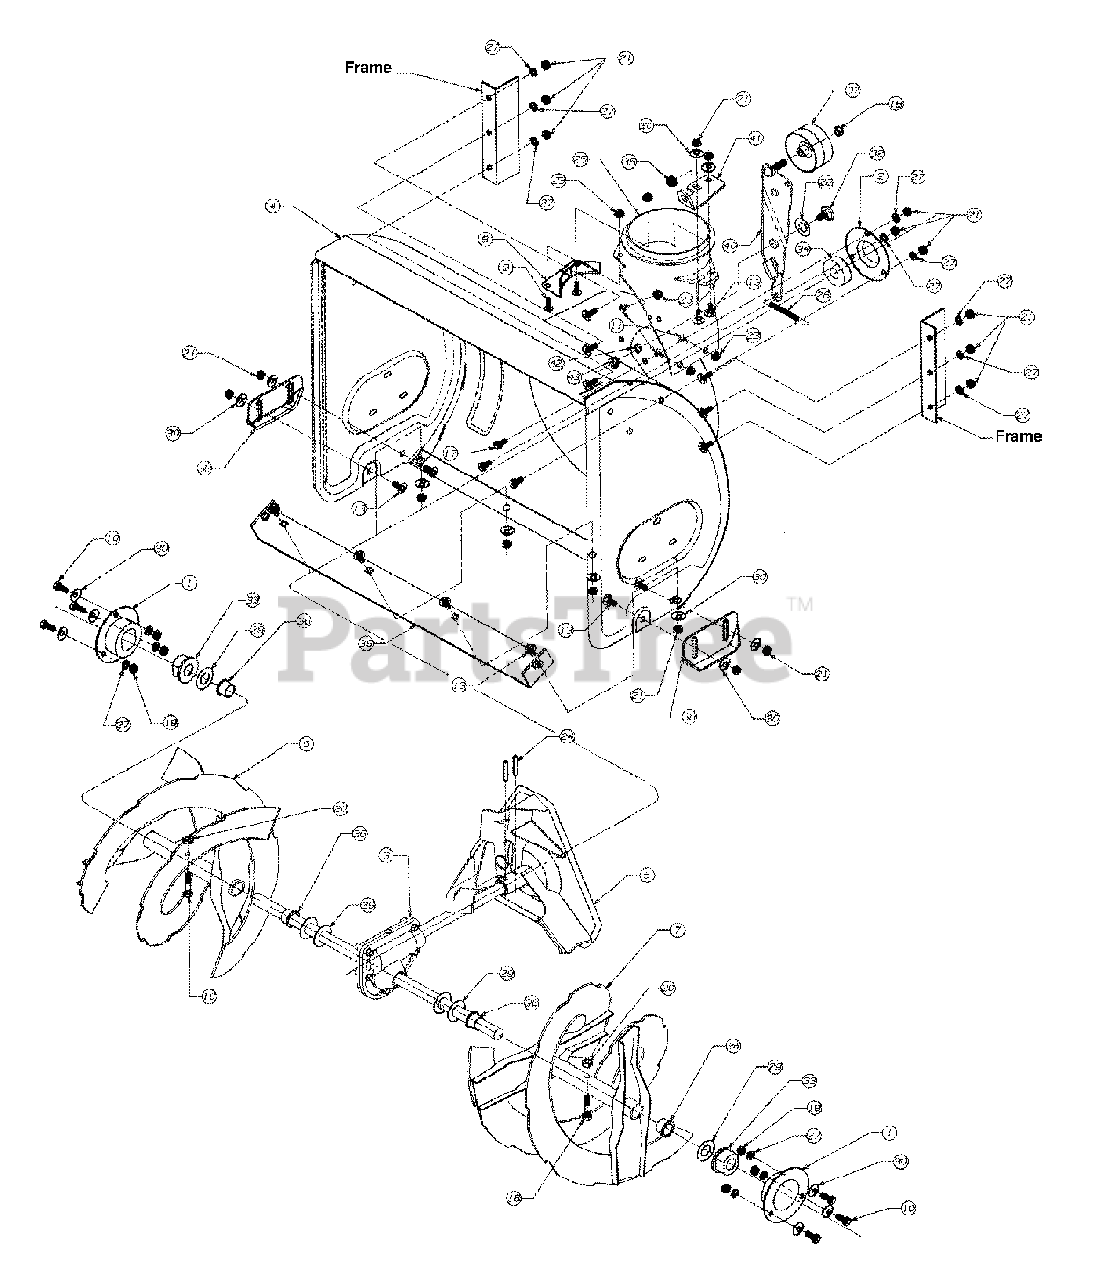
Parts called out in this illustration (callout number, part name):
1	Housing, Bearing
2	Housing, Bearing
3	Gear Assembly
4	22" Housing Assembly
4	24" Housing Assembly
4	26" Housing Assembly
4	30" Housing Assembly
5	Impeller Assembly
6	Spiral, 22" R.H.
6	Spiral, 24" R.H.
6	Spiral, 26" R.H.
6	Spiral, 30" R.H.
7	Spiral, 22" L.H.
7	Spiral, 24" L.H.
7	Spiral, 26" L.H.
7	Spiral, 30" L.H.
9	Bolt, Carriage
10	Screw, Hex
11	Screw, Carriage
13	Screw, Carriage
16	Bolt, Shear
18	Hex Lock Nut
20	Nut, Hex Lock
21	Nut, Hex
23	Nut, Lock, Hex, Flanged
24	Spring Pin
25	Adapter, Chute
26	Spring
27	Lock Washer
28	Washer, Flat
29	Washer, Flat, .76 I.D. x 1.49 O.D. x .06
30	Washer, Bell
32	Screw, Shoulder
33	Bearing, Flange
34	Bearing, Ball
35	Bushing, Plastic
36	Bushing, Flange
37	Idler, Flat
38	Shoe, Slide
39	22" Shave Plate
39	24" Shave Plate
39	26" Shave Plate
39	30" Shave Plate
40	Arm, Auger Idler
41	Bracket, Chute Crank
42	Lock Washer
43	Hex Nut
